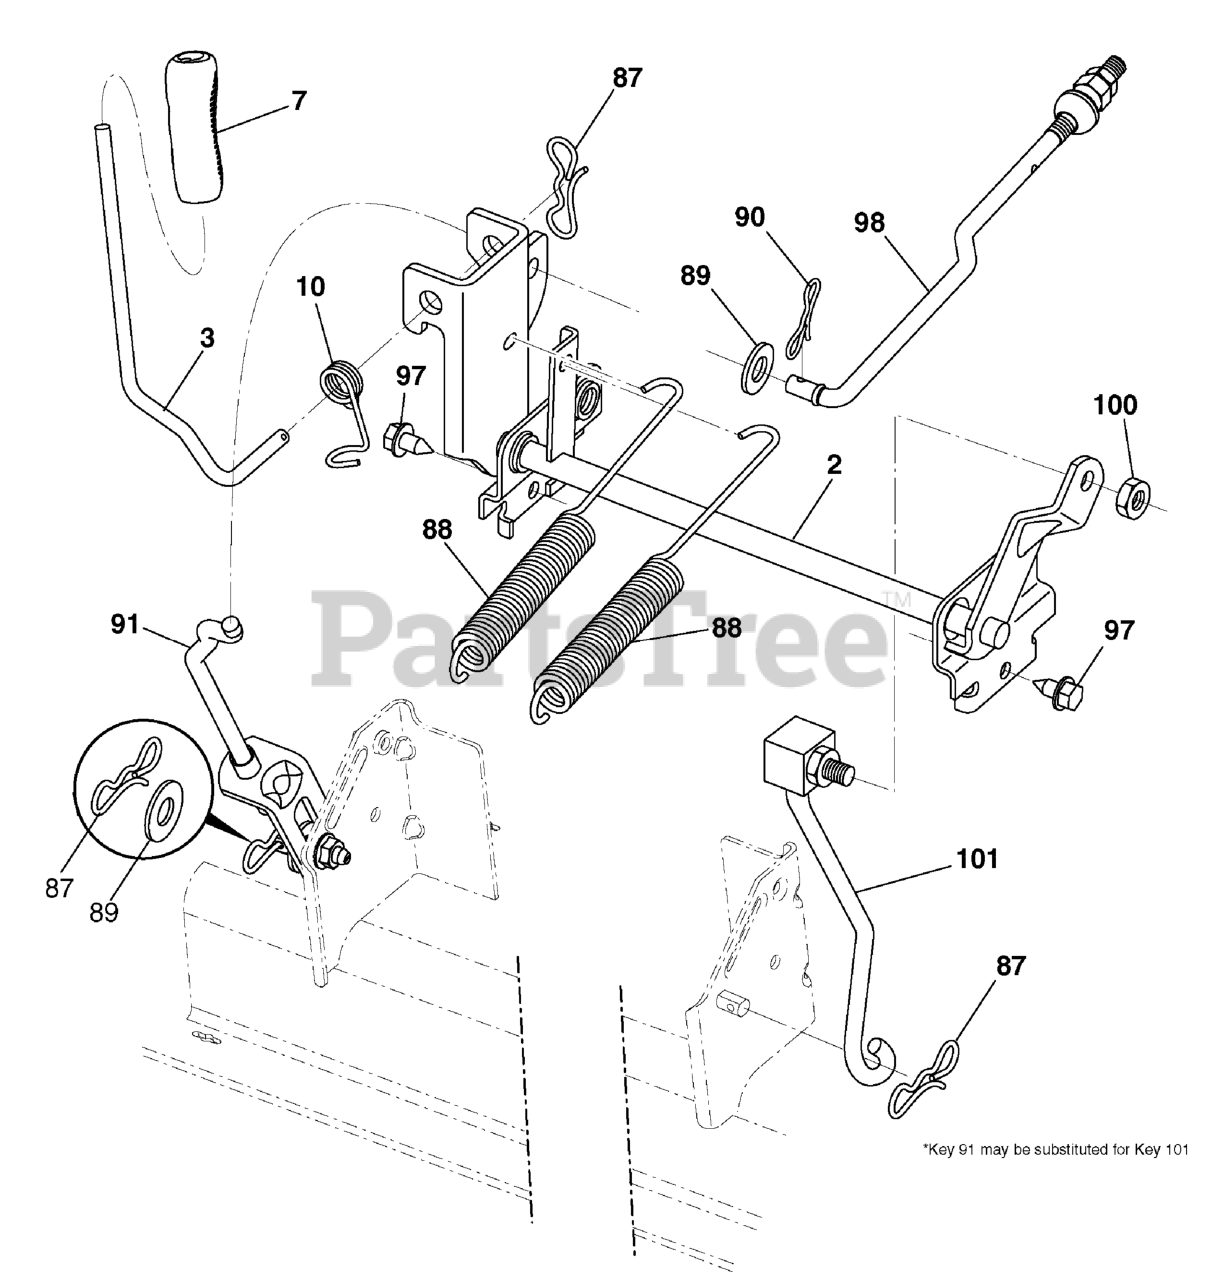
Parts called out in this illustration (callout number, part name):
2	Shaft Asm., Lift
3	Lever Asm., Lift RH
7	Grip, Lever
10	Spring Torsion
87	Pin Cotter 7/16 Bow Tie Lock
88	Spring Lift Assist
89	Washer Clear Zinc
90	Pin Cotter 5/16 Bow Tie Lock
91	Link Lift Susp Mower Rear
97	Screw 3/8-16 x 3/4
98	Link Lift Susp. Front Mower
100	Nut Lock 3/8-16
101	Link Asm. Lift Fixed
